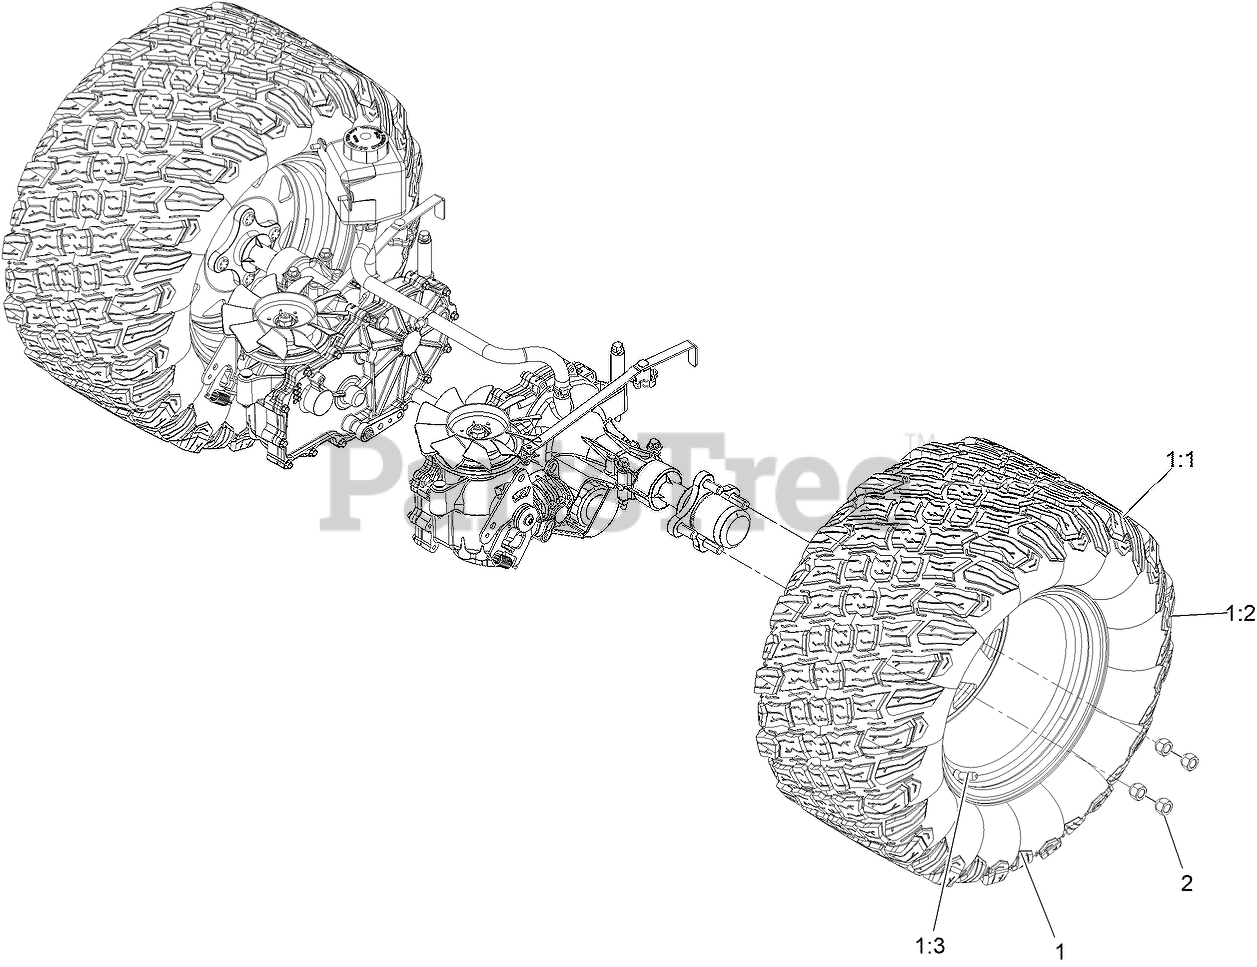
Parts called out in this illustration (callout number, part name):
1	ASM-WHEEL AND TIRE
1:1	Wheel-12X8.5
1:2	Tire-Kenda K3012
1:3	Stem-Valve
2	NUT-LUG
